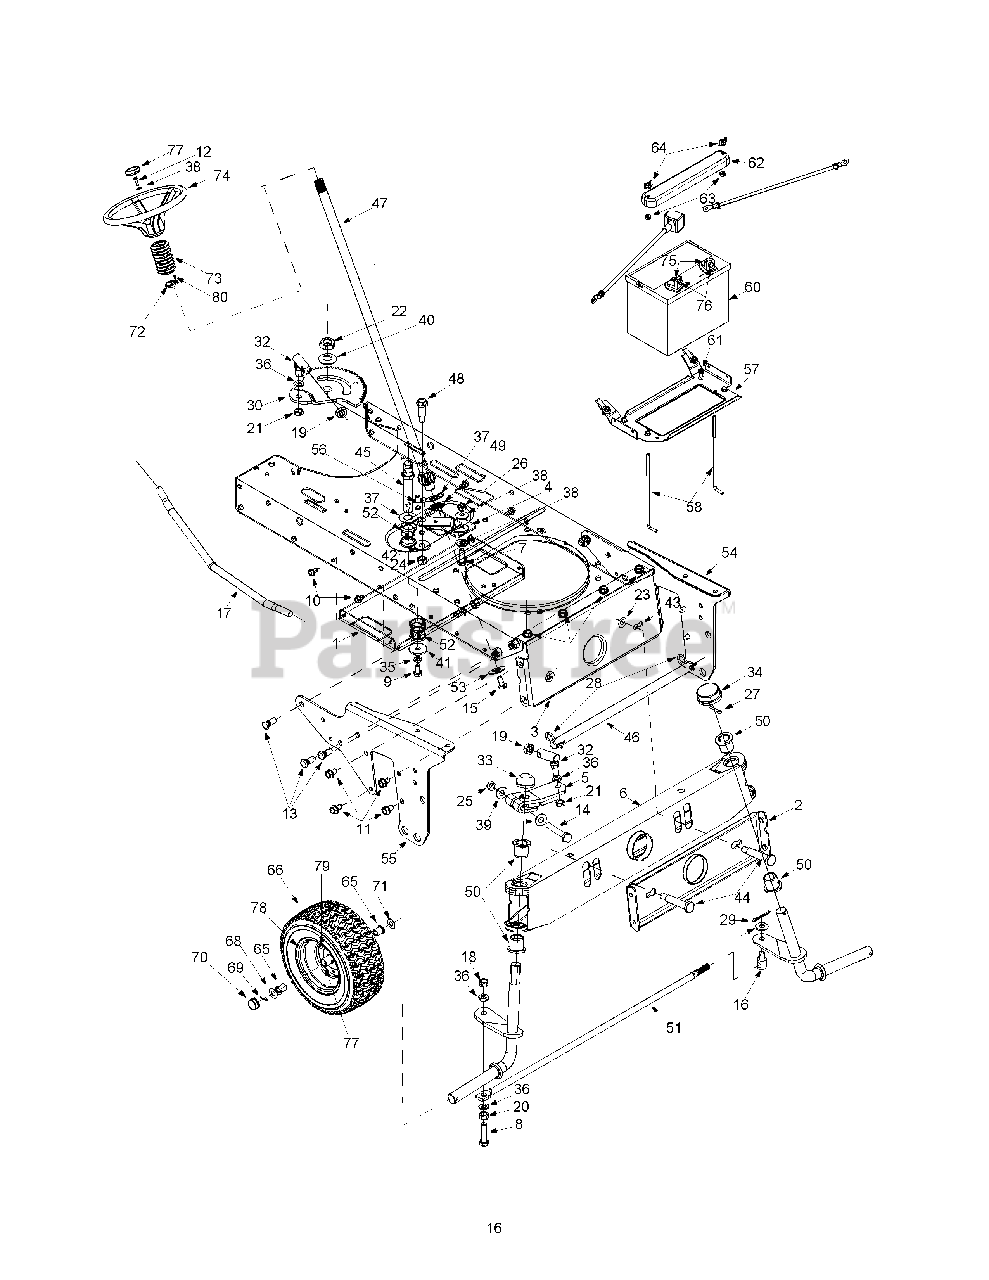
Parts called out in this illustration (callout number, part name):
7	Hex Bolt 5/16-24 x 1.0"
8	Hex Bolt 3/8-24 x 1.50"
9	Hex Bolt 5/16-18 x 0.625"
10	TT Screw 1/4-20 x 0.5"
11	TT Screw 5/16-18 x 0.625"
12	Hex Bolt 5/16-18 x 1.0"
13	Rib Neck Rd. Bolt
14	Hex Bolt 3/8-24 x 2.5"
15	Pan Hd. Machine Screw
16	Ferrule
17	Steering Drag Link
18	Hex Lock Nut 3/8-24
19	Jam Nut
20	Hex Nut 3/8-24
21	Lock Nut
22	Jam Nut
23	Flange Lock Nut
24	Hex Nut 3/8-16
25	Lock Nut
26	Hex Nut
27	Cotter Pin
28	Hairpin Clip
29	Cotter Pin
30	Steering Gear Segment: 25T
32	Ball Joint
33	Push Cap
34	Hub Cap
35	Lock Washer
36	Lock Washer
37	Flat Washer
38	Beleville Washer
39	Flat Washer
40	Bell Washer
41	Flat Washer
42	Bell Washer
43	Grease: Alvania (TM)
44	Shoulder Screw
45	Steering Gear Shift Segment
46	Deck Rod
47	Steering Shaft
48	Shoulder Screw
49	Hex Flange Bearing
50	Flange Bearing
51	Tie Rod
52	Hex Flange Bearing
53	Cap
60	Battery
61	Hex Washer B-Tap Scr.
62	Battery Cover
63	Hex Nut
64	Wing Nut
65	Flange Bearing
66	Wheel
68	Flat Washer
69	Cotter Pin
70	Hub Cap
71	Flat Washer
72	Flange Bearing (Style A only)
73	Steering Bellow (Style 0, 3,5,9)
74	Steering Wheel
75	Hex Lock Nut
76	Hex Bolt 1/4-20 x .75"
77	Steering Cap (Round)
79	Air Valve
80	Oval Hd. C-Sunk Screw
81	Pivot Bar Cap End
82	Grease
83	Axle Assembly LH: Front
